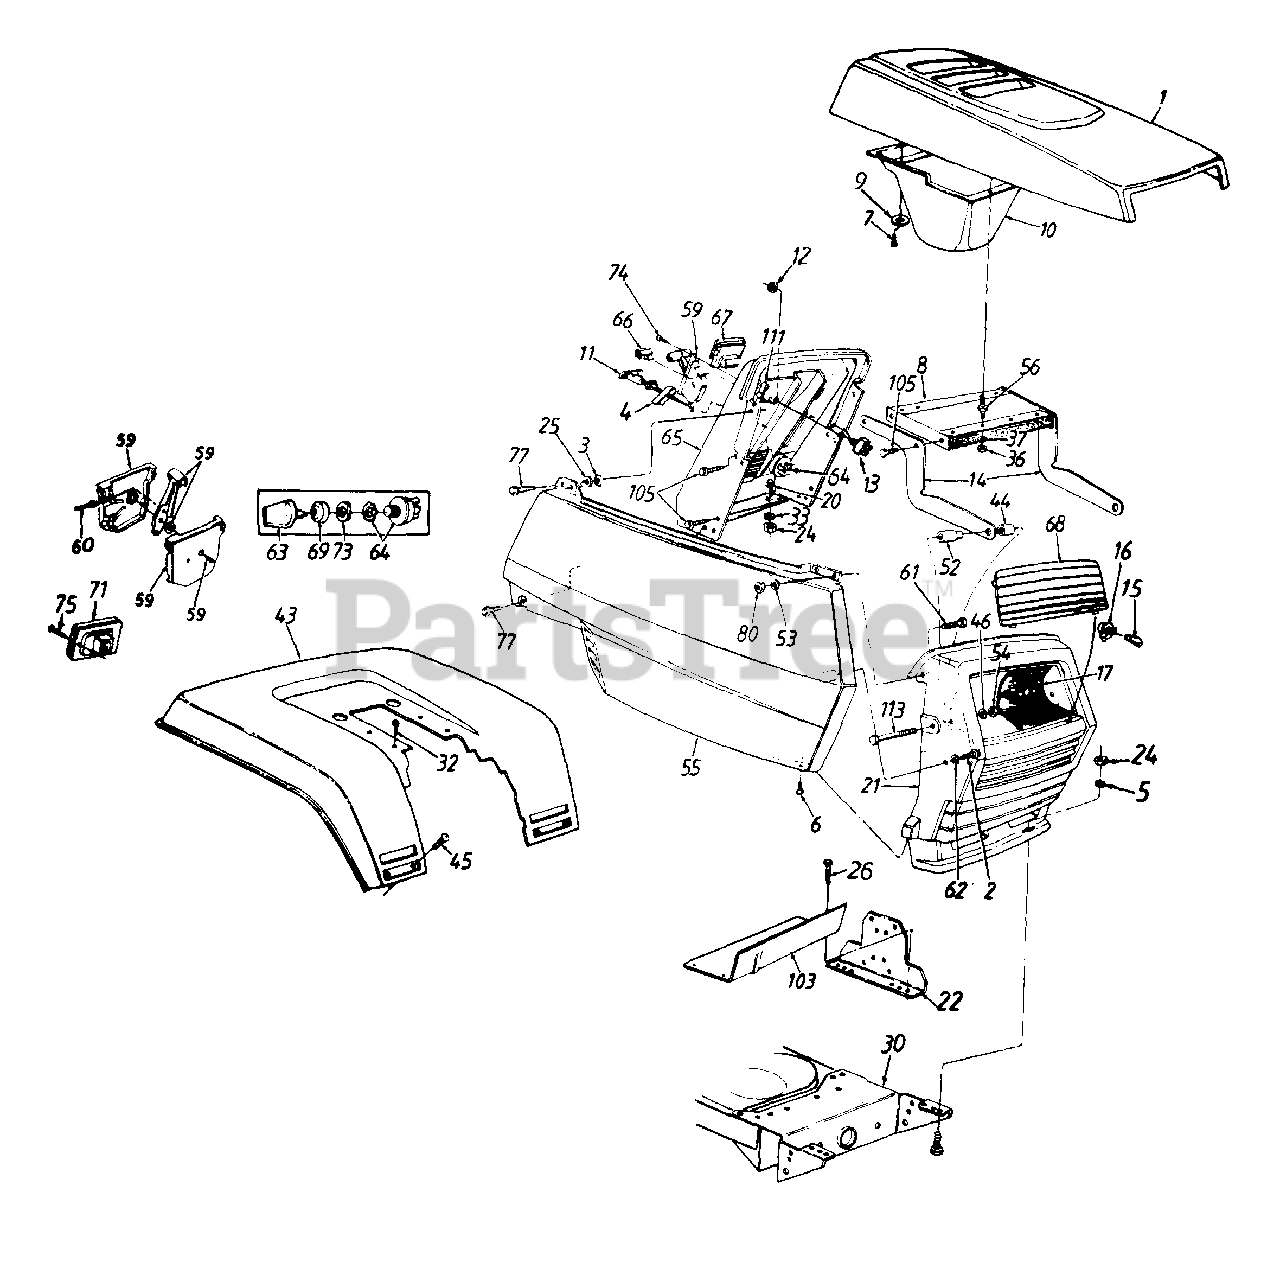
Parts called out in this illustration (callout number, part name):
1	Hood
2	Hex Wash. B-Tap Scr. 1/4 x .62" Lg.
3	Bolt Retainer 1/4" I.D.
4	Retainer Clip
5	Fl-Wash. .34" I.D. x 1"
6	Truss Mach. B-Tap Scr. #10 x .5" Lg.
7	Hex Wash. Hd. AB-Tap Scr. #8 x .5" Lg.
10	Air Plentum
11	Choke Control
12	Hex Nut 1/2-27 Thd.
13	Toggle Switch
14	Hood Hinge
15	Lamp
16	Twist Lock - Lamp Socket
17	Reflector - Headlight
20	Hex Bolt 5/16-18 x .75" Lg.
21	Grille
25	Fl-Wash. 1/4" I.D. x .93" O.D.
26	Hex Wash. Hd. B-Tap Scr. 5/16-18 x .5" Lg.
32	Hex Wash. Hd. AB-Tap Scr. 5/16 x .75" Lg.
33	Bell-Wash. .345" I.D. x .88"
36	Hex Nut 1/4-20 Thd.
37	Bell-Wash. .265" I.D. x .75"
45	Carriage Bolt 1/4-20 x .50" Lg
46	Fl-Wash. .328" I.D. x .68" O.D.
52	Shld. Spacer .33" I.D.
53	Fl-Wash. .281" I.D. x .5" O.D.
54	Hex Cent. L-Nut 5/16-18 Thd.
55	Side Cover - R.H.
56	Double Ended Stud 1/4-20 Thd.
59	Throttle Control Box Ass'y.
60	Throttle Control Wire 35" Lg.
61	Hex Bolt 1/4-20 x .62" Lg.
62	Fl-Wash. .281" I.D. x .73" O.D.
64	Ignition Switch
65	Dash Panel
66	Light Switch
67	Ammeter
68	Lens
69	Ignition Switch Cap
71	Taillight
73	Ignition Switch Nut
74	Truss Mach. AB-Tap Scr. #10 x .5" Lg.
75	Truss Hd. AB-lap Scr. #6 x .62" Lg.
77	Hex Wash. Hd. Tap Scr. 1/4 x .75" Lg.
80	Hex L-Nut 1/4-20 Thd.
111	Speed Nut 1/4-20 Thd.
113	Hex Bolt 5/16-18 x 2.75"
